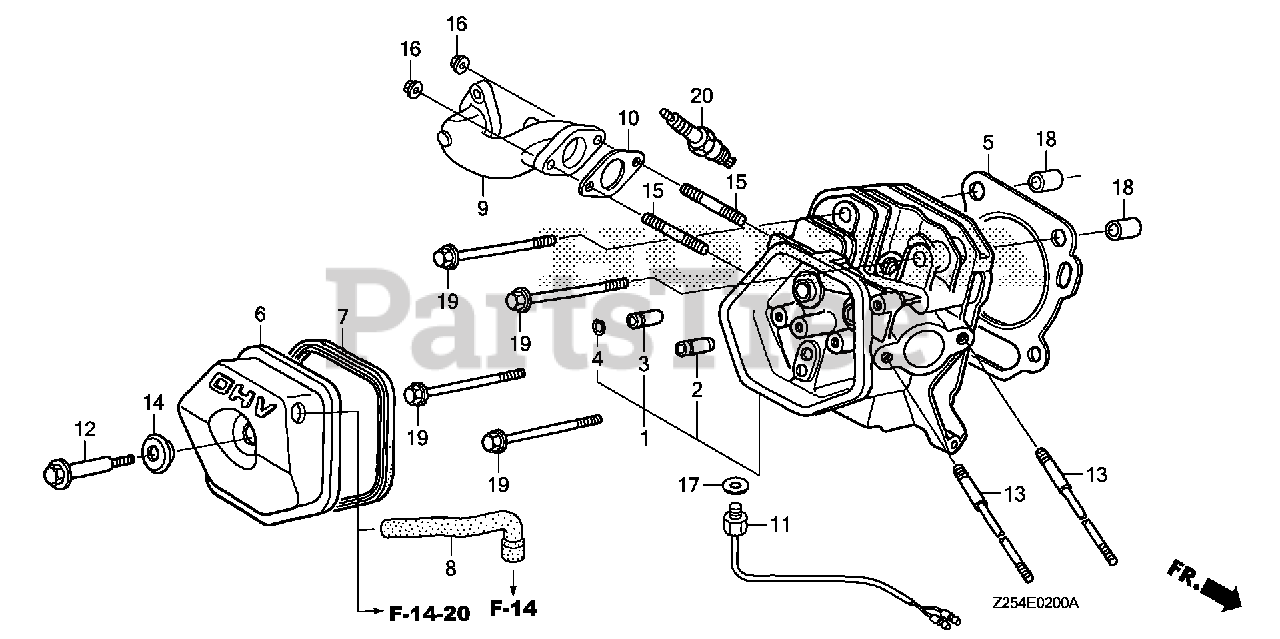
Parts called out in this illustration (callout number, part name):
1	CYLINDER HEAD
2	GUIDE, VALVE (OVER SIZE)
3	GUIDE, EX. VALVE (OVER SIZE)
4	CLIP, VALVE GUIDE
5	GASKET, CYLINDER HEAD (NIPPON LEAKLESS)
6	COVER, HEAD
7	GASKET, HEAD COVER
8	TUBE, BREATHER
10	GASKET, EX. PIPE
11	SENSOR ASSY., TEMPERATURE
12	BOLT, HEAD COVER
13	BOLT, STUD (8X126.5)
14	WASHER, HEAD COVER
15	BOLT, STUD (8X32)
16	NUT, FLANGE (8MM)
17	WASHER, PLAIN (8MM)
18	PIN, DOWEL (12X20)
19	BOLT, FLANGE (10X80)
20	SPARK PLUG (BPR6ES) (NGK)
20	SPARK PLUG (W20EPR-U) (DENSO)
